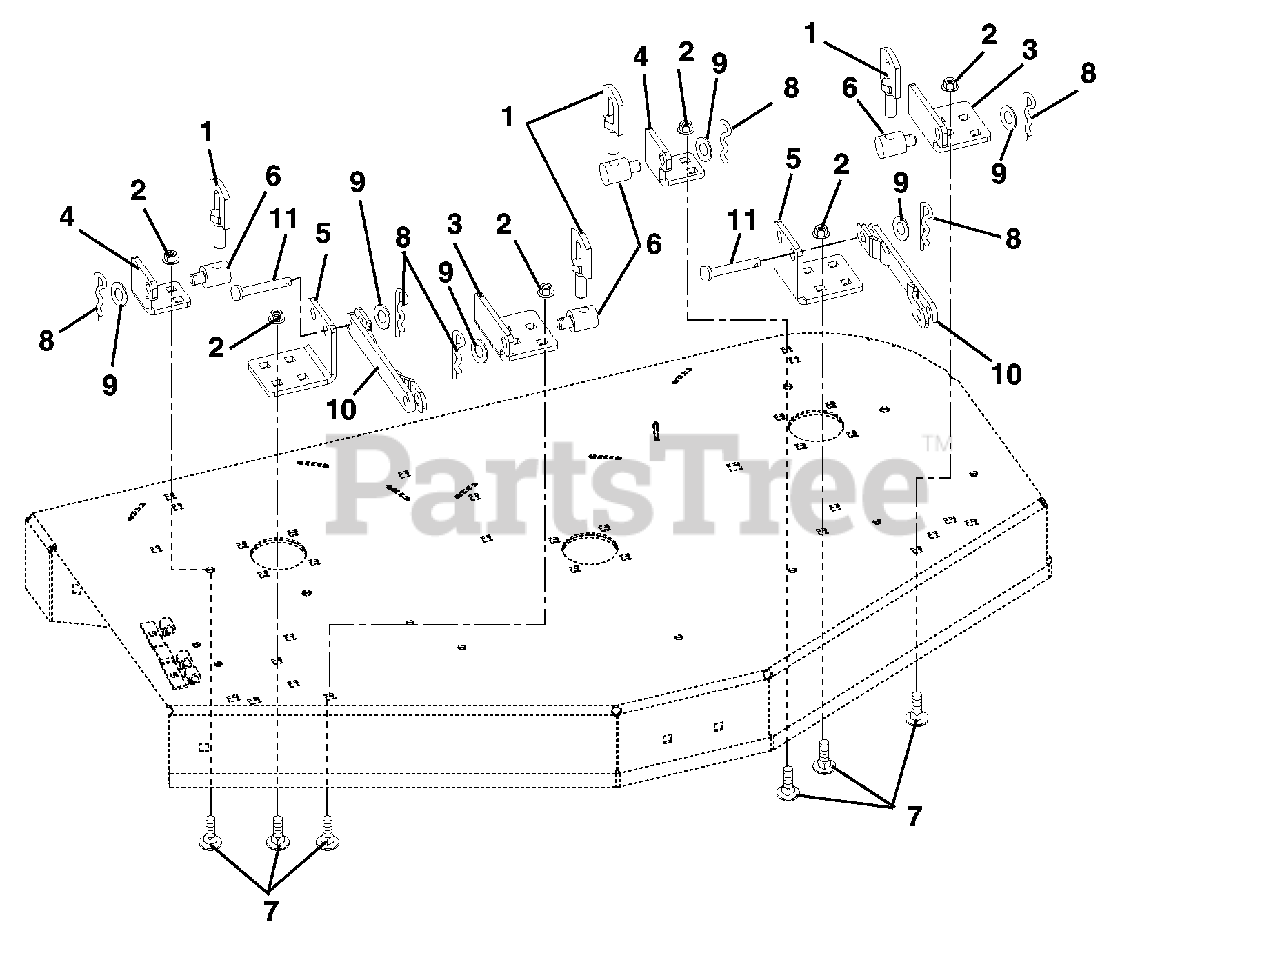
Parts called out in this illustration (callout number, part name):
1	WELDMENT, ADJUSTMENT LINK
2	NUT-LK-TOP-FLG .38-16 BLKZC
3	BRACKET, MOUNT,FRONT
4	BRACKET, REAR MOUNT
5	BRACKET, STABILIZER
6	TRUNNION-.50
7	BLT-RDHDSQNK .38-16X.75 G5BZ
8	PIN, HAIR, EXT - #16 YWZC
9	WSHR-FL-STL.511X1.441X.125 BZ
10	WMT, STABILIZER ARM
11	PIN-CLEV .494X1.25 YWZC
